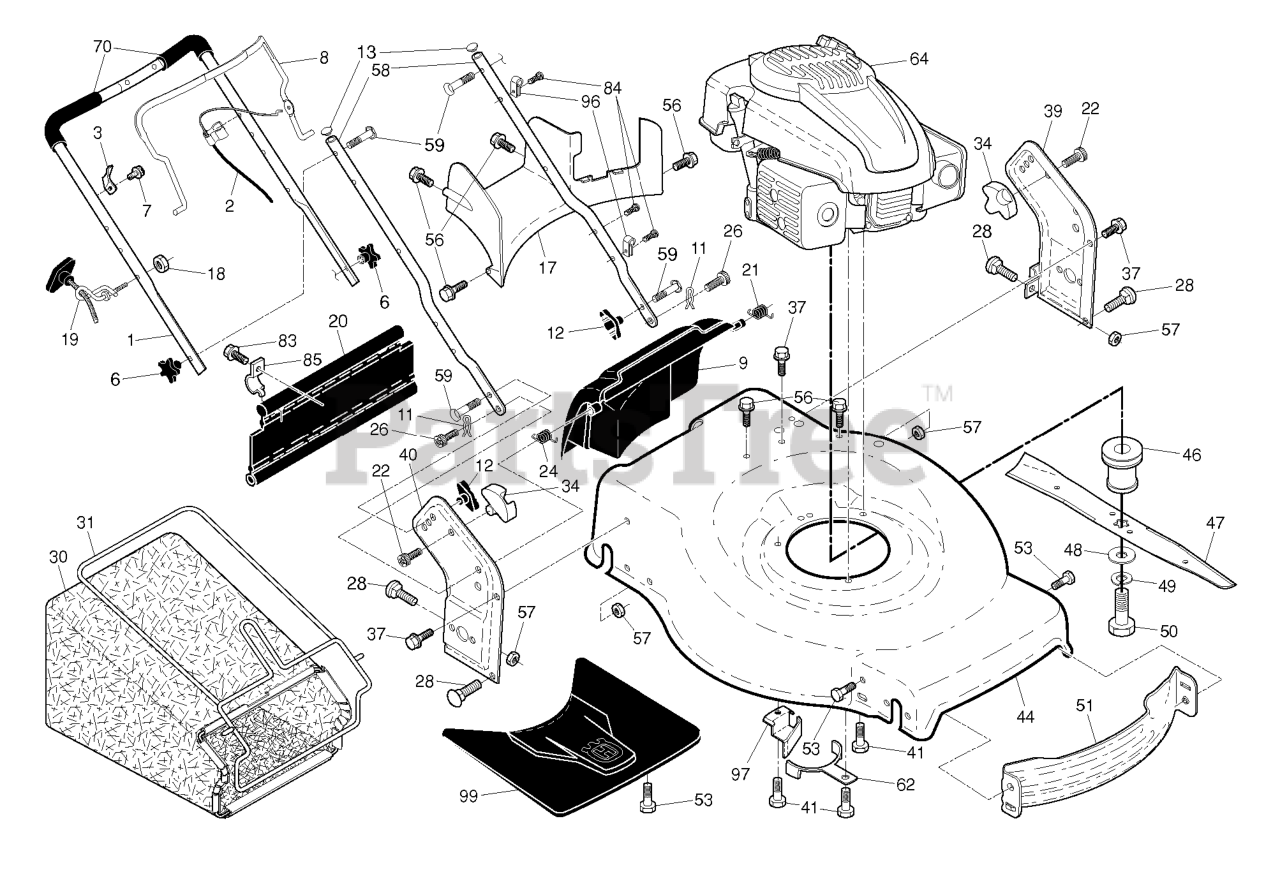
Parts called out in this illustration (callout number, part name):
1	HANDLE.ASM.GRY.W/GRIP
2	CABLE.MZR.RGD.KOHLER.STRT
3	BRACKET.UPSTOP.RT
6	KNOB.HANDLE.PLASTIC.STAR.BLACK
8	BAIL.MZR.EZ2.DSTR.22+.ORG.E
9	DOOR.REAR.ASM.22+.HUSQ.FG/RGD
11	COTTER.HAIRPIN.DOOR/HANDLE.PIV
12	KNOB, DEFLECTOR
13	PLUG.PLASTIC.7/8".14-20.GAUGE
17	RP.BAFFLE.REAR.22+.RGD.PL
18	NUT
19	RB GUIDE.ROPE.STD.BLK.ZIN WSL
20	SKIRT.REAR.22PLUS.RGD/FGD.NEW
21	SPRING.LH.BLACK
22	SCREW.PAN.HEAD.#10
24	SPRING.RH.GRAY
26	SCREW,DOOR/HANDLE.PIVOT
28	BOLT
30	GBAG.A3610247T.SILV.HUSWT.BLUE
31	RB FRAME.GBAG.22PLUS
34	BRACKET.GRASSBAG.ATTACHING.BLK
37	BOLT.5/16HEX.WHS.HD
39	BRACKET.ASM.HANDLE.LT
40	RP.BRACKET.ASM.HANDLE.RT.22+.
41	BOLT 3/8-16X1-1/8
44	HOUSING.22+.RWD.WO/PORT.ORANGE
46	ADPTER.BLAD.25M.VS.22PLU.STAR
47	BLADE.22+FUSION.PREM/PREC
48	WASHER,HARDEN
49	LOCKWASHER
50	SCREW, HEX HD 3/8-24 X 1-3/8
51	BAFFLE.FRONT.22PLUS.PLASTIC RP
53	SCREW.HI-LO.5/16 X.75
56	SCREW.HX.13X.750
57	NUT.FLANGE.5/16
58	HANDLE.LOWER.22+BT.2PC.GRY
59	BOLT, HANDLE 5/16-18X1.75
62	BRACKET.KEEPER.BELT
70	GRIP.HANDLE.FOAM.WIDE.(1 SIDE)
83	TAPPING SCREW
84	FASTENER.PUSH.O.250X0.783
85	BRACKET.SKIRT.22+.BZP
96	CLIP.CABLE.BLK
97	BRACKE.BELT.GUIDE.22+
99	COVER.ASM.FRONT.SHROUD.HUSQ.
